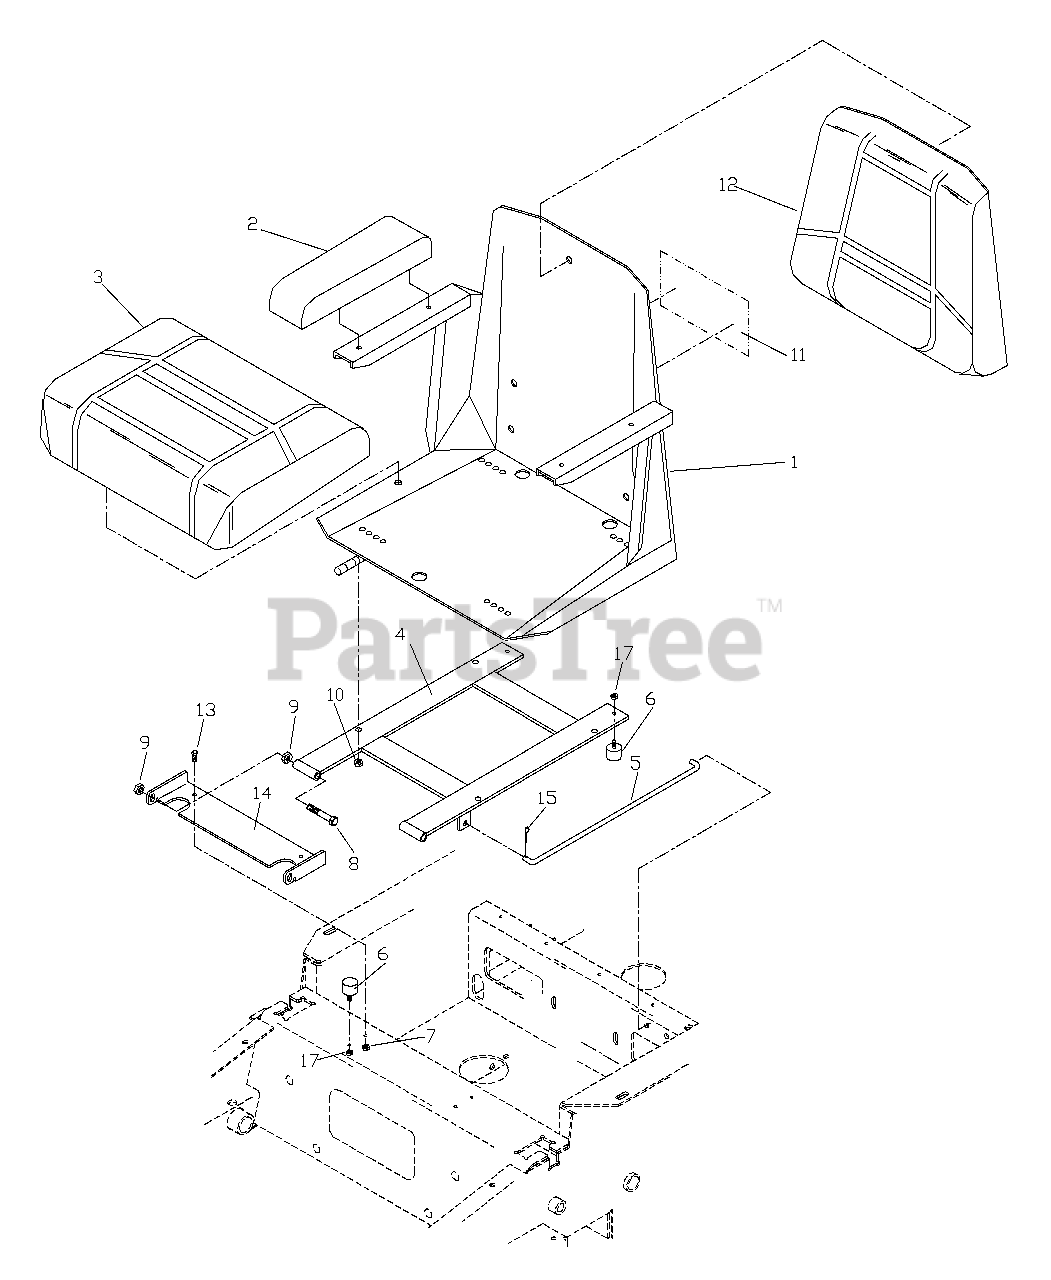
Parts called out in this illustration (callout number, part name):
1	SEAT COMPLETE
2	ARM REST CUSHION
3	SEAT CUSHION
4	SEAT MOUNT
7	NUT 1/4 LOCK
8	HCS 3/8 X 3.0
9	NUT 3/8 LOCK
10	NUT 5/16 LOCK
11	DECAL, CROWN
12	BACK CUSHION
13	HCS 1/4 X 3/4
14	SEAT BRACKET W/DECAL
15	COTTER PIN
16	SEAT RAILS
17	NUT 1/4 NYLOC
18	SEAT HARNESS
19	SEAT SWITCH
